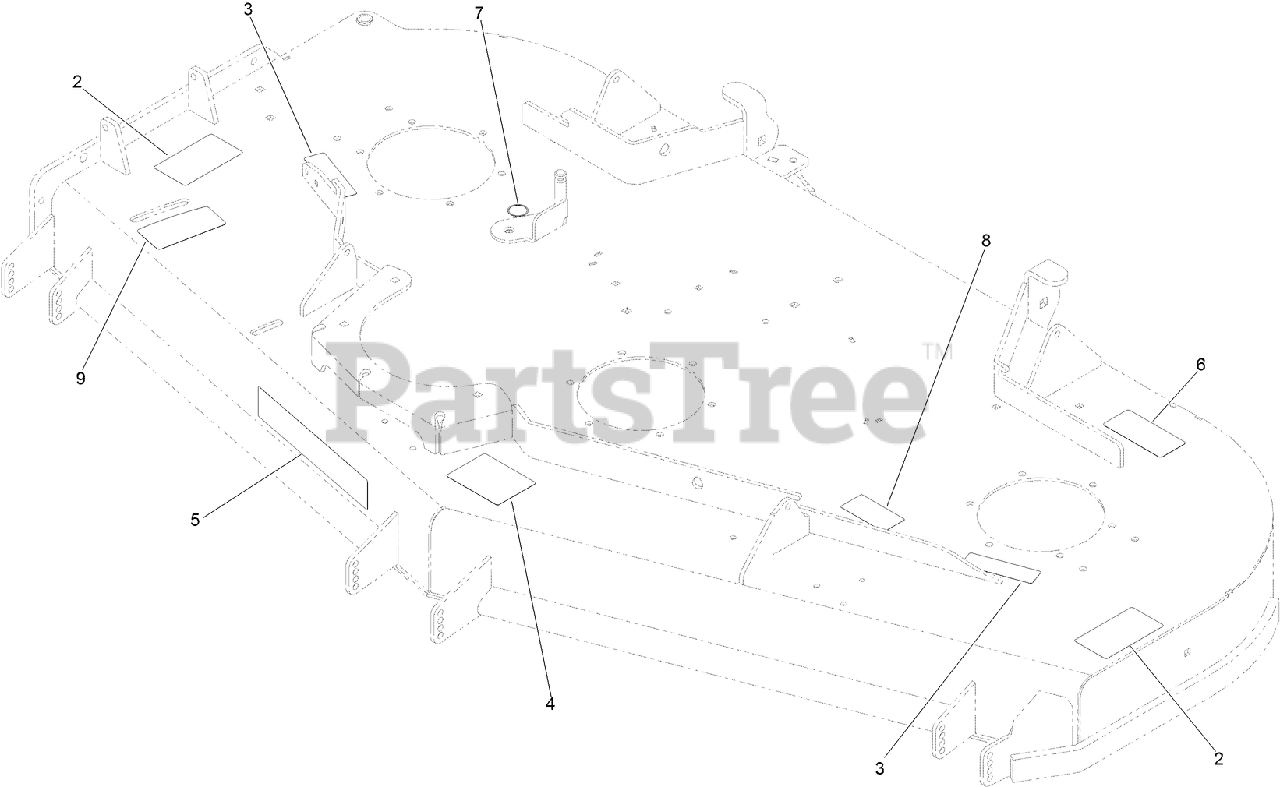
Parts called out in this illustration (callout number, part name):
2	DECAL-DANGER THROWN OBJECTS
3	DECAL-COVER, MISSING
4	DECAL-SCALP, ANTI
6	DECAL-TORQUE, BLADE BOLT
7	DECAL-GREASE
8	DECAL-BELT ROUTING
9	DECAL-ADJUSTMENT, BAFFLE
